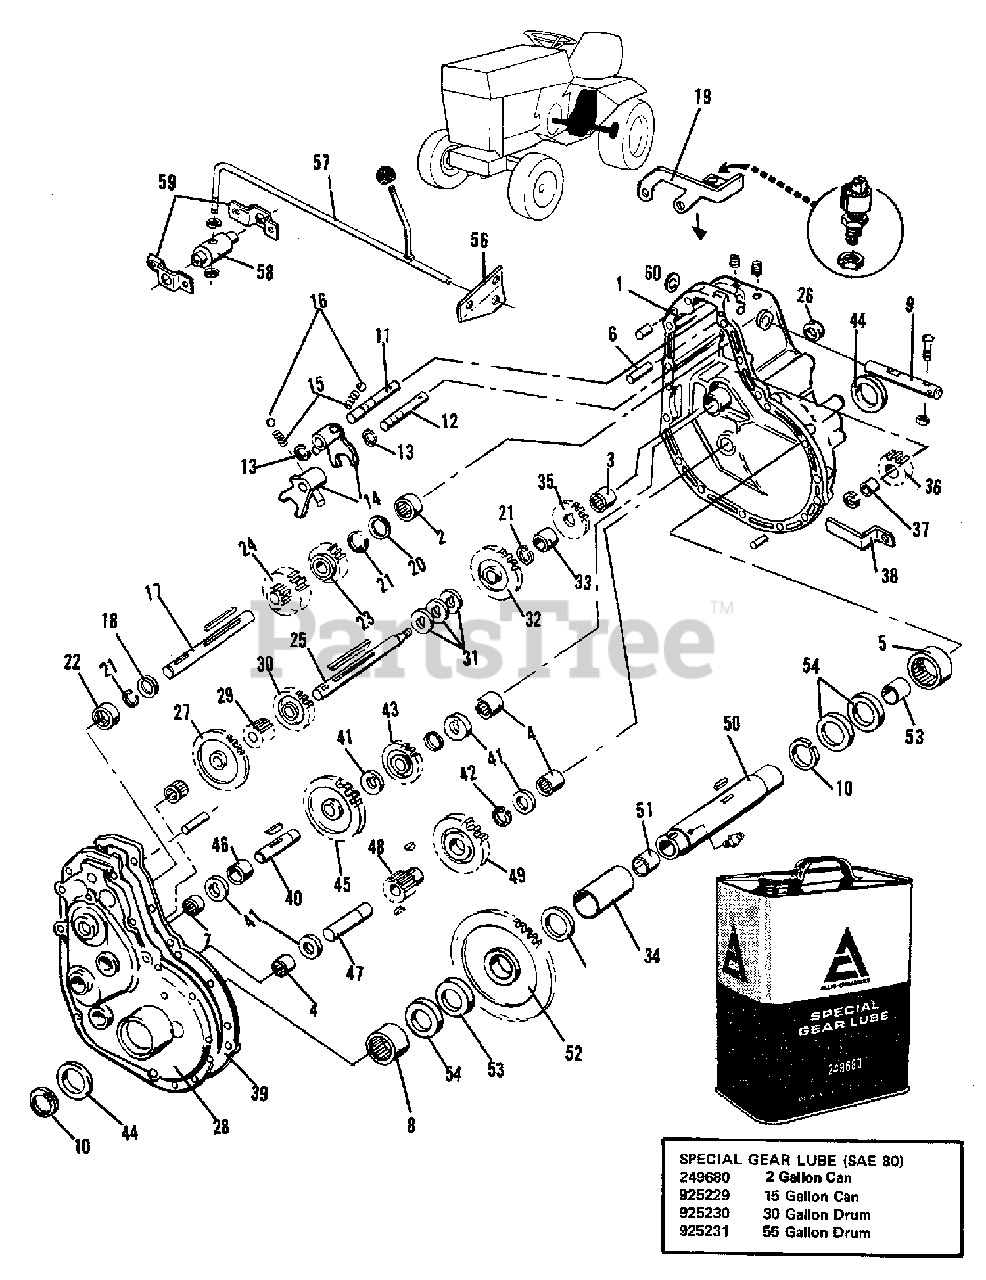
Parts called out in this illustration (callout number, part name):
1	CASE, Gear Sub-Assembly (Includes Items 2 thru 6)
1	PIN, Roll, 3/8 x 1
1	SETSCREW, Socket Head, 5/16NC x 1/2
1	SPACER, Differential
1	SEAL, Oil
2	BEARING, Needle
3	BEARING, Needle
4	BEARING, Needle
5	BEARING, Needle
6	ROLL PIN SUB ASSEMBLY
7	BEARING, Needle
8	BEARING, Needle
9	ROD, Shift
9	NUT, Jam, 5/16NC
9	BOLT, 5/16NC x 1
9	NUT, 3/8NF
9	STEM, Shift
10	RING, Snap
11	SHAFT, Shifter, Reverse & Medium
12	SHAFT, Shifter, High & Low
13	RING, Retaining
14	FORK, Shift
16	BALL, Shift Lock
17	SHAFT, Pulley
17	KEY, Pulley Shaft
18	RING, Retaining
19	SUPPORT, Switch
21	RING, Retaining
22	BEARING, Ball
22	RING, Retaining (Outside Of Bearing)
23	PINION ASSEMBLY, Reverse & 2nd
24	PINION ASSEMBLY, 1st & 3rd
25	SHAFT, 1st Intermediate
25	KEY, Intermediate Shaft
26	SEAL, Oil
27	GEAR, Driven 1st
28	COVER ASSEMBLY, Gear Case (Includes BEARINGS)
28	PLUG, Pipe, 3/8 Standard Square Head
28	CAPSCREW, Hex. Head, 5/16NC x 1
28	LOCKWASHER, 5/16 Reg.
29	PINION, 1st Intermediate
30	PINION, Driven 3rd
31	SPACER, Transmission Gear
32	GEAR, Driven 2nd
33	SPACER, 2nd & Reverse
34	SPACER, Axle Tube
35	PINION, Reverse
36	GEAR, Reverse
37	SPACER, Reverse Gear
38	PIN ASSEMBLY, Reverse Gear
38	NUT, Lock 1/2NF
38	CAPSCREW, 3/8nc x 1-1/4
38	WASHER, Reverse Gear Pin
39	GASKET, Gear Case
40	SHAFT, 2nd Intermediate
40	KEY, 2nd Intermediate Shaft
42	RING, Retaining
43	PINION, 2nd Intermediate
44	SEAL, Oil
45	GEAR, 2nd Intermediate
47	SHAFT, 3rd Intermediate
48	PINION, 3rd Intermediate
48	KEY, Woodruff #6, 5/32 x 5/8
49	GEAR, 3rd Intermediate
50	TUBE ASSEMBLY, Axle (Includes BUSHING)
50	FITTING, Tube, 1/4NC x 1/2
50	KEY, Axle Tube
51	BUSHING, Axle Tube
52	GEAR, DRIVE
53	WASHER, Axle Tube
55	OIL, Transmission
56	SUPPORT, Gear Shift Lever
57	ROD ASSEMBLY, Shift
57	BALL, Shift Lever
57	E-RING, External
58	PIVOT, Shift Rod
59	SUPPORT, Shift Rod Pivot
59	CAPSCREW, 5/16NC x 1-1/4
59	NUT, 5/16NC
59	LOCKWASHER, 5/16
59	CAPSCREW, 5/16NC x 5/8
60	SEAL, Oil
